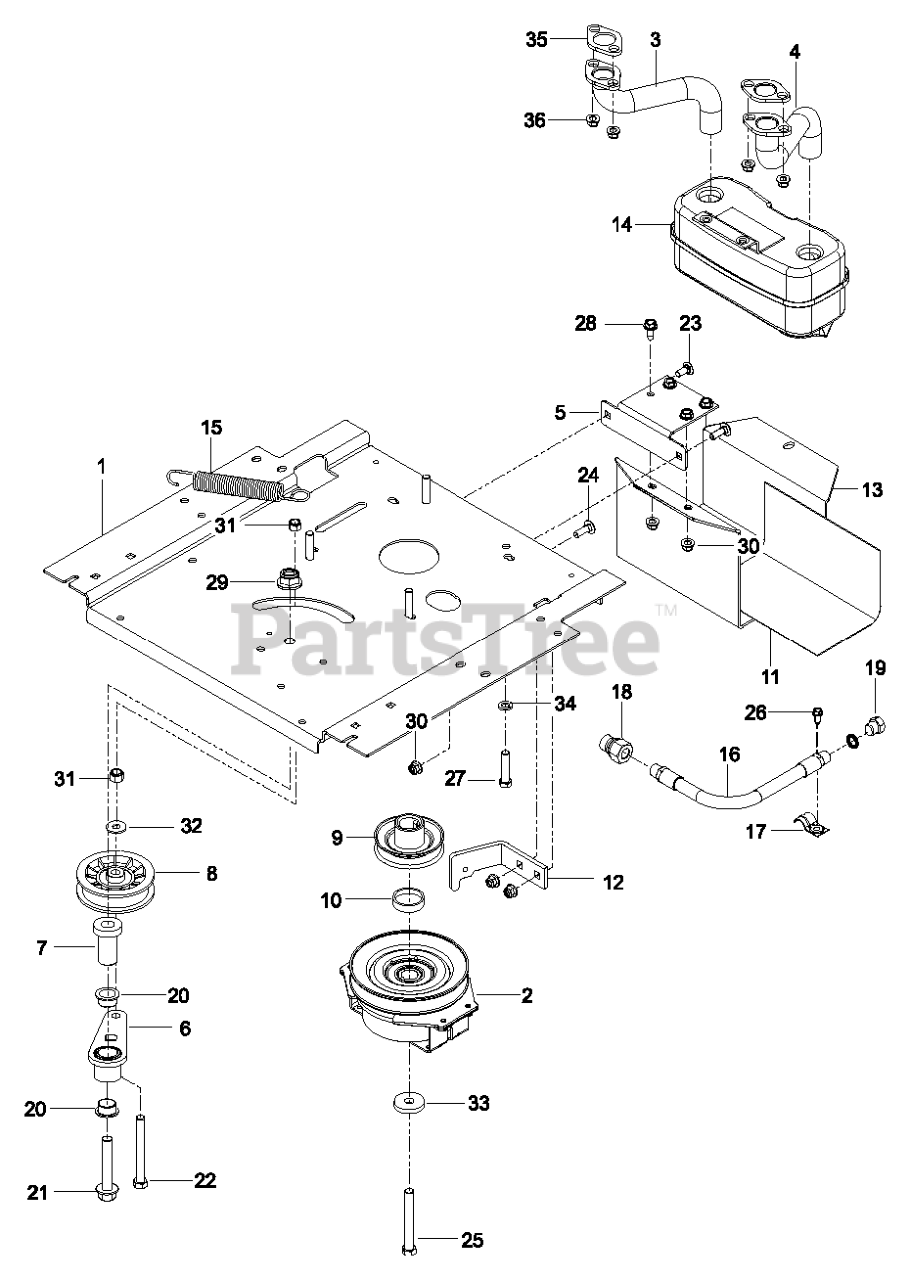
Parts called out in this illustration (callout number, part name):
1	PLATE ENGINE; RZ, 23IN BLACK
2	CLUTCH.OGURA.5.0PD.GT1.5A-EH07
3	TUBE.EXHAUST.RH.FR961/FR730
4	TUBE.EXHAUST.LH.FR961/FR730
5	BRACKET MUFFLER MS431BLK
6	ARM IDLER
7	SPINDLE.IDLER
8	PULLEY, IDLER RAKE & ZTR
9	PULLEY.ENGINE
10	SPACER.SPACER.625 W/OGURA.LCC
11	HEAT SHIELD
12	CLUTCH.STOP.OGURA LCC.BLACK
13	GUARD.MUFFLER.WO.TOW.HITCHX431
14	MUFFLER ASM TWIN
15	SPRING, DECK DRIVE
16	HOSE.ASSEMBLY.OIL.DRAIN
18	ADAPTER, OIL DRAIN
19	PLUG OIL DRAIN
20	BEARING.FLANGED.PLASTIC.3/4ID
21	BOLT.FLANGE.1/2-13 X 2.75.GRD5
22	HCS 3/8-16X3-1/2 TAPBLT GR5 ZD
23	BOLT 5/16C X 3/4" CARRIAGE
24	RHSNB 5/16C X 1
25	CLUTCH BOLT7/16-20X2.5 GR524HR
26	SCR 1/4-20X5/8 HEX SELF TAP ZD
27	BOLT
28	SCREW.THDROL.5/16-18X3/4.TTY
29	NUT, 1/2-13 HEX FLG NYLOC ZD
30	5/16-18 NYLOC FLANGE NUT
31	NUT 3/8-16 NYLOC
32	WASHER.5/16.FLAT.STE.STD.
34	SLW 3/8 STD
36	NUT.HEX.FLANGE.TOPLOCK
